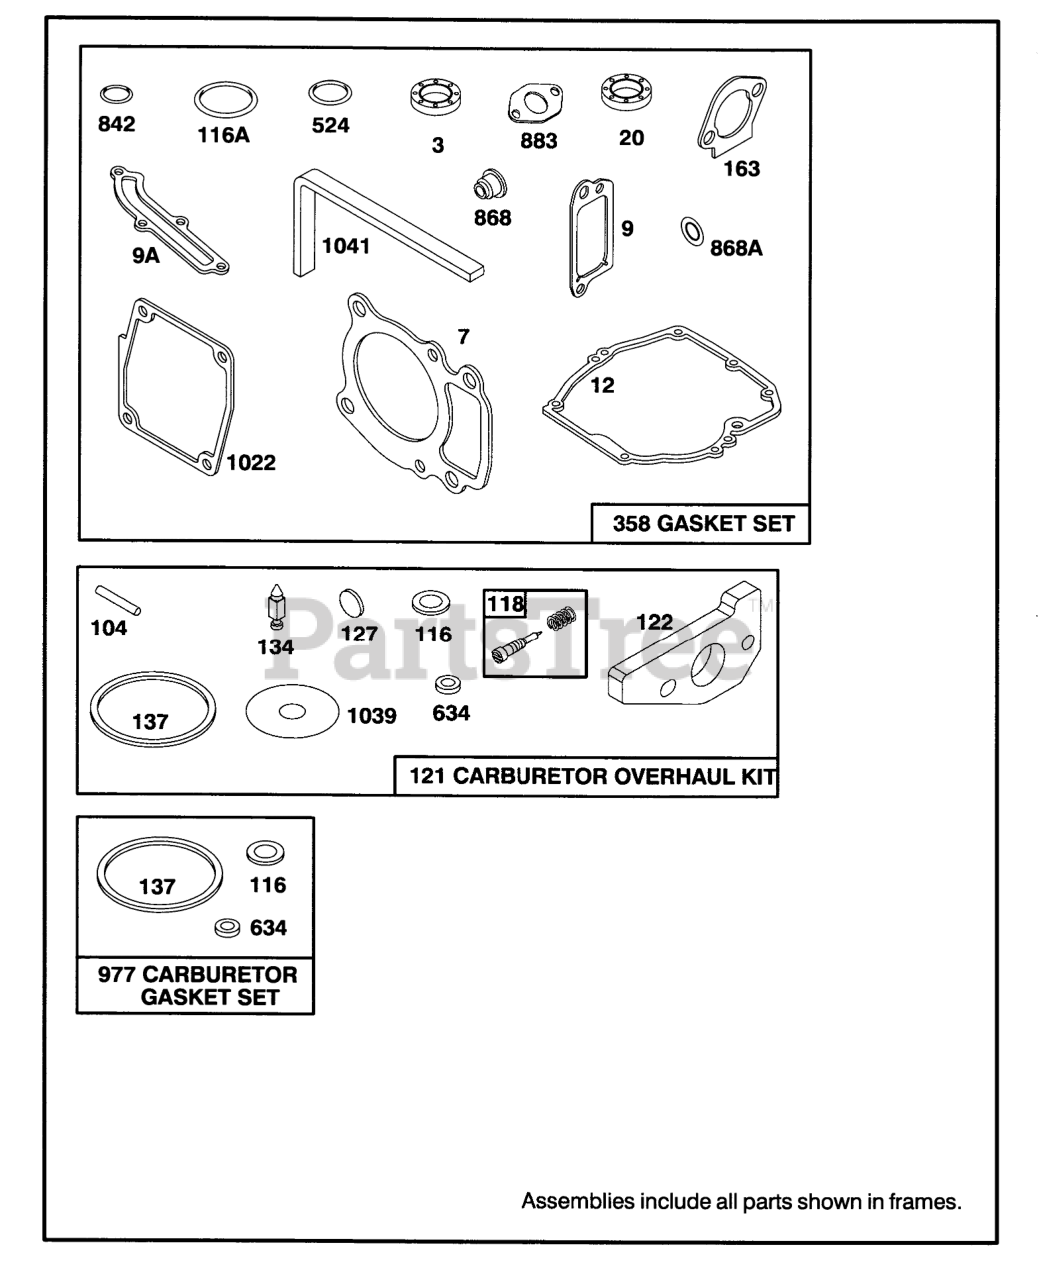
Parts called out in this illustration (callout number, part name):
3	SEAL - OIL
7	CYLINDER HEAD GASKET
9	BREATHER GASKET
9A	GASKET-BREATHER
12	ENGINE BASE GASKET
20	SEAL-OIL
104	FLOAT HINGE PIN
116	SEALING GASKET
116A	O RING SEAL
118	VALVE KIT - NEEDLE
121	CARBURATOR OVERHAUL KIT
122	ADAPTER ASSEMBLY
127	PLUG
134	Valve-Float (Includes Seat)
137	FLOAT BOWL GASKET
163	AIR CLEANER GASKET
358	GASKET SET
524	O-RING
634	SEAL WASHER
842	O-RING
868	SealAssy-Valve
868A	Seal-Valve
883	EXHAUST GASKET
977	CARBURATOR GASKET SET
1022	ROCKER COVER GASKET
1039	FLOAT LIMITER
1041	SEAL - FOAM
